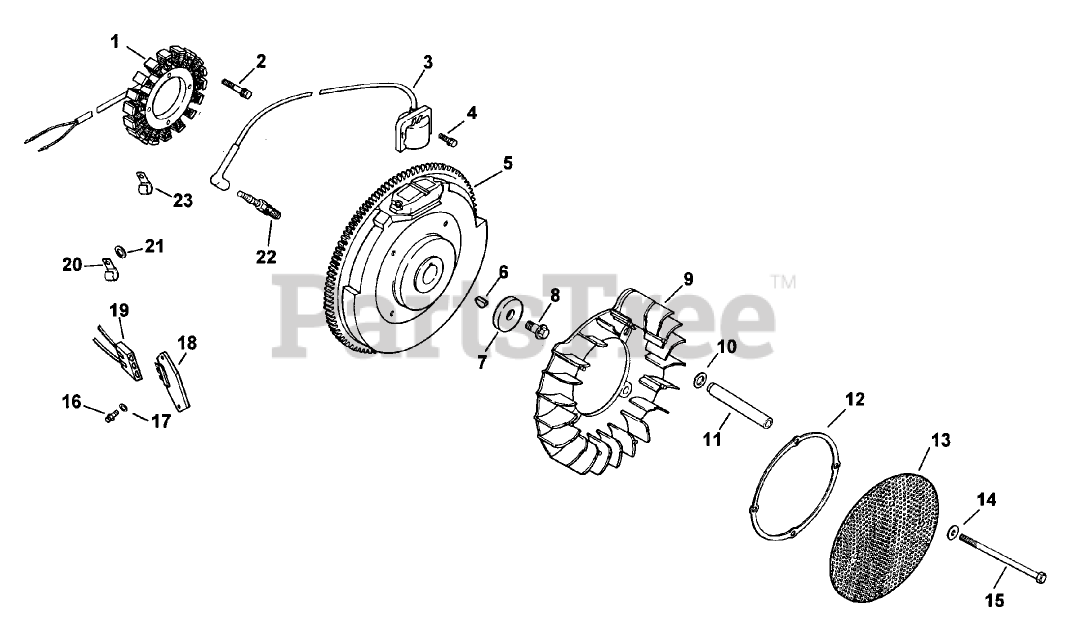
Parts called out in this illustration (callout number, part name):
1	Stator-15 amp
2	Screw
3	Module-Ignition
4	Screw
5	Flywheel
6	Key
7	Washer
8	Screw
9	Fan
10	Washer, sping
11	Spacer
12	Ring-Support
13	Screen-Grass
14	Washer
15	Screw-Hex
16	Screw
17	Washer
18	Rectifier-Regulator
19	Connector
20	Clip
21	Washer
22	Plug-Spark
23	Clip
